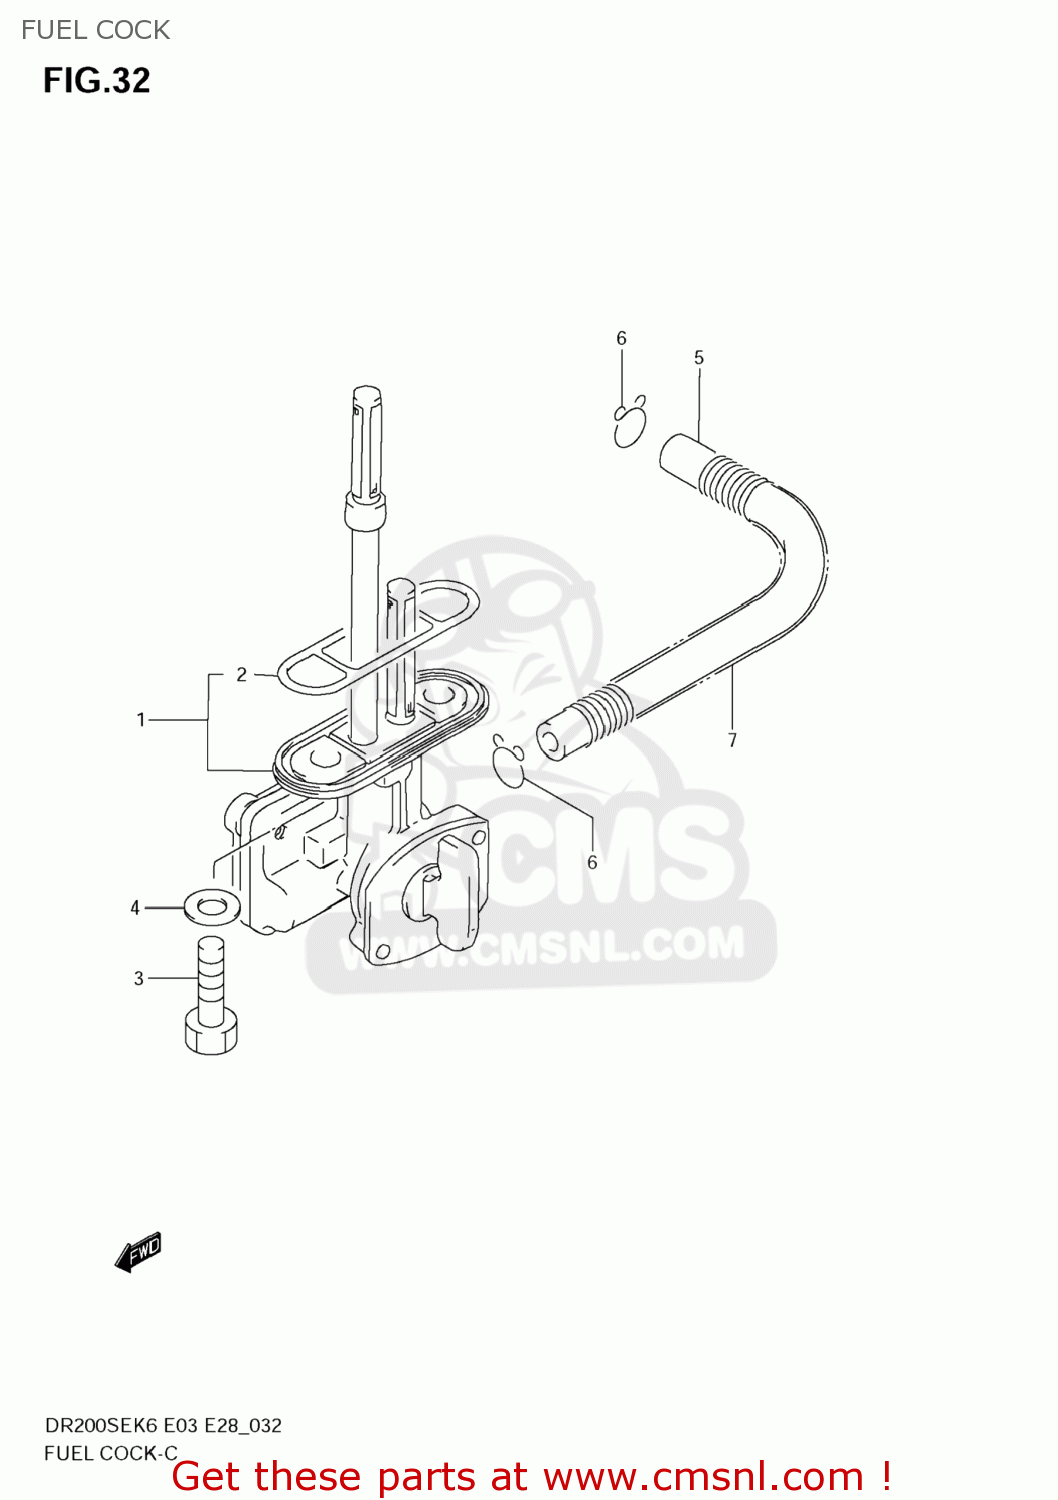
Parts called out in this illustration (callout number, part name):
1	COCK ASSY,FUEL
2	GASKET,JOINT (NAS)
3	BOLT(6X20)
4	GASKET(6.4X11.5X0.8) (NAS)
5	HOSE(5X8.2X600)
6	CLIP
7	SPRING
